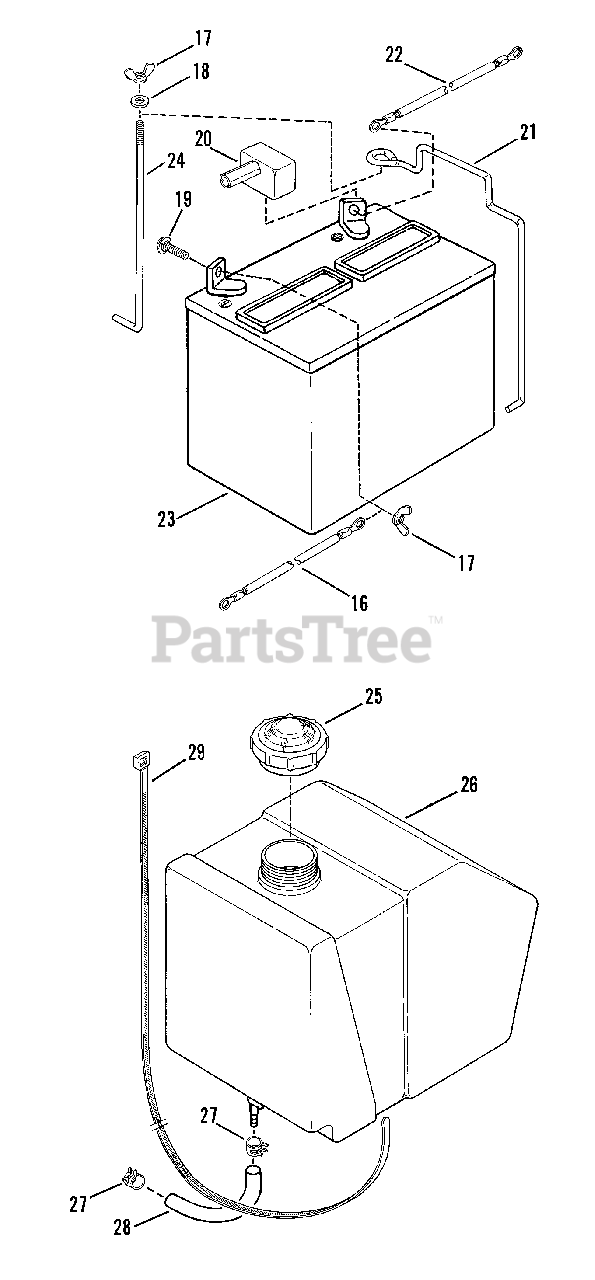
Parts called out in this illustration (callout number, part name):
16	CABLE, Negative Terminal
17	WING-NUT, 1/4-20
18	WASHER, 1/4 SAE
19	BOLT, 1/4-20 x 3/4" Short Neck Carr.
20	COVER, Positive Terminal
21	CLAMP, Battery
22	CABLE, Positive Terminal
23	KIT, Battery, 12 Volt
24	HOLD-DOWN, Battery
25	CAP, Fuel Tank
26	TANK, Fuel
27	CLAMP, Fuel Line
28	LINE, Fuel
29	CABLE-TIE, Fuel Tank Hold-Down
